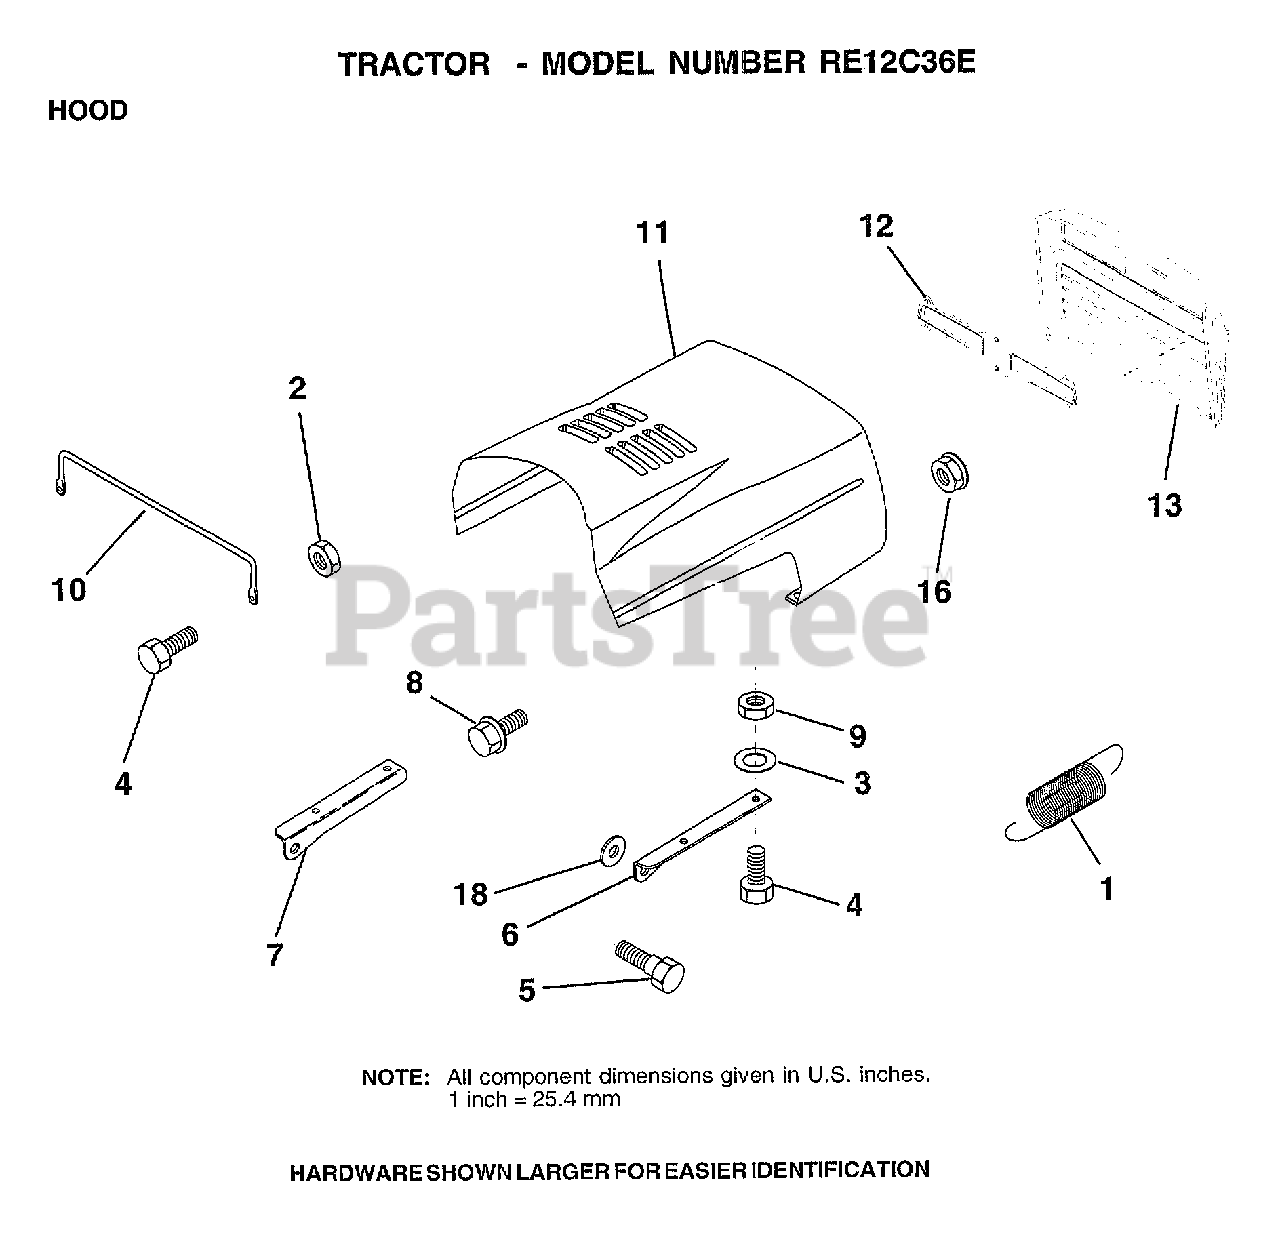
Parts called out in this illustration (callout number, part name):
1	EXT SPRING
2	NUT
3	WASHER
5	BOLT.SHLD.5/16-18
6	BRKT HOOD RH
7	BRKT HOOD LH
8	"SCREW,HWHD.HI-LO#13-16X3/4"
9	NUT
10	"BRACE,HOOD"
11	HOOD
13	GRILL (BLACK)
16	NUT
18	WASHER
